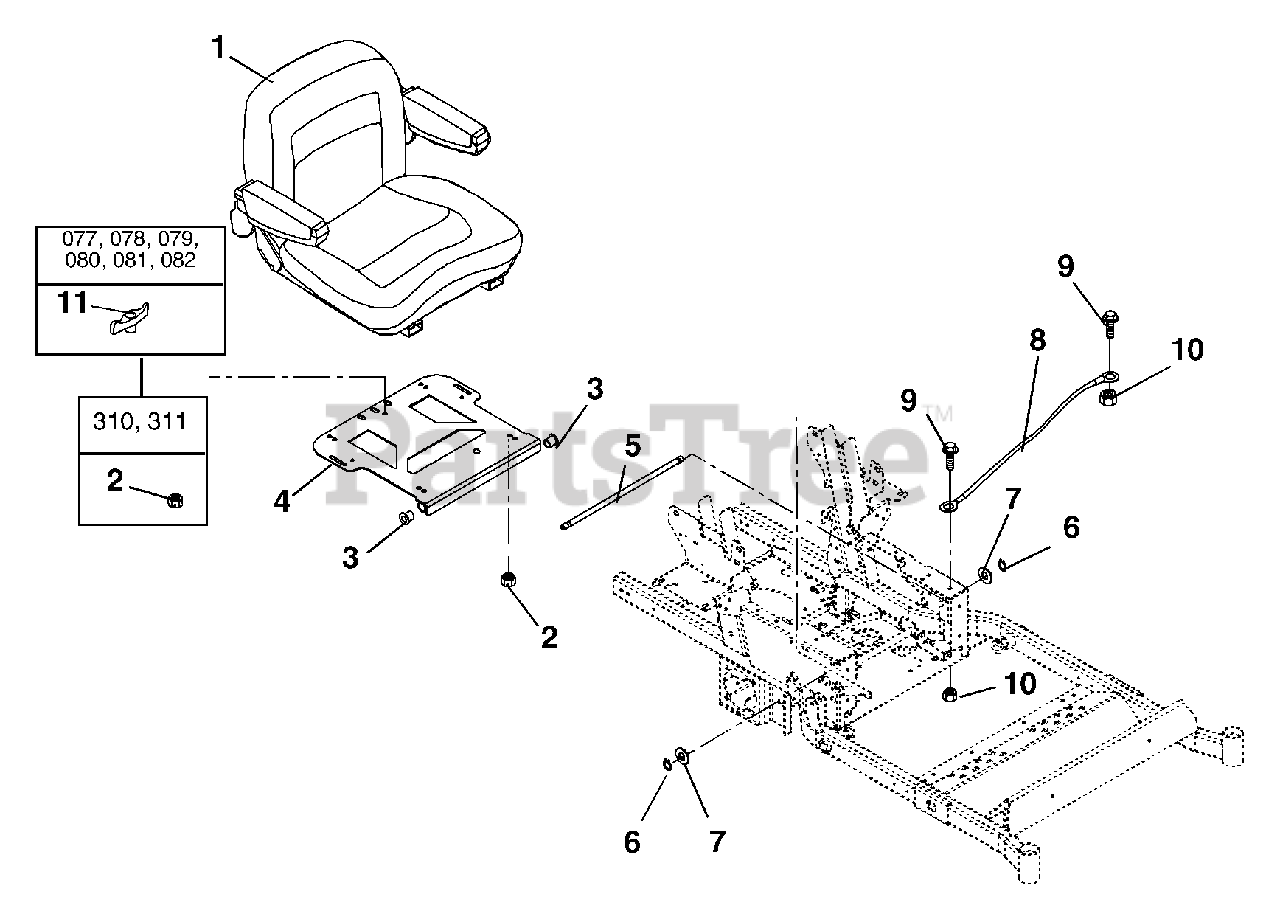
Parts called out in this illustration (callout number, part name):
2	Nut, Locking Top Flange .31-18 (077, 078, 079, 080, 081, 082)
2	Nut, Locking Top Flange .31-18 (310, 311)
3	Bushing, Flange .515 x .750 x .745 x 1.00
4	Seat Pivot Mount
5	Rod, Seat Frame Pivot
6	Ring, Retaining External .500 x .050
7	Washer, Thrust 1.14 x 1.50 x .20
8	Cable, Hood
9	Bolt, Hex .25-20 x .75 Grade 5
10	Nut, Locking Top Flange .25-20
11	Knob, Wing .312-18 (077, 078, 079, 080, 081, 082)
